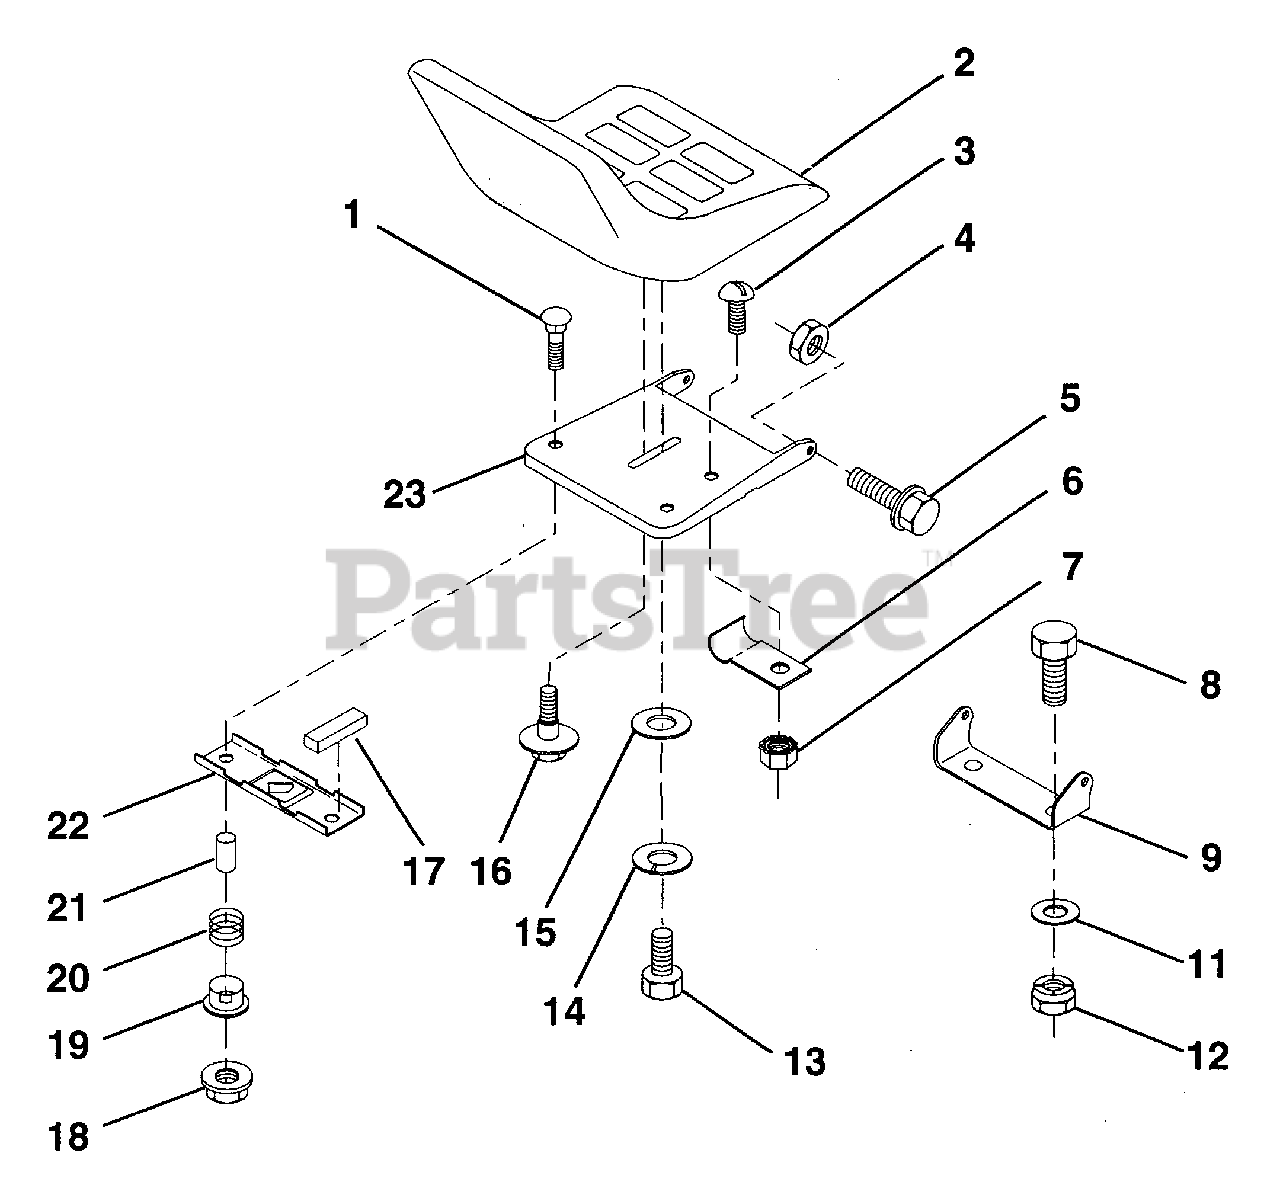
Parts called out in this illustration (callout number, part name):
1	Bolt, Carriage 1/4-20 x 1-3/8
2	Seat
3	Screw, Slotted Pan Head #10-32 x 1/2
4	Nut, Crownlock 5/16-18
5	Bolt, Shoulder 5/16-18 UNC
6	Clip, Insulated
7	Nut, Hex, Keps #10-32 UNF
8	Bolt, Hex, Fin. 3/8-16 UNC x 3/4
9	Bracket, Pivot, Seat
11	Washer 12/32 x 2 x 10 Gauge
12	Nut, Crownlock 3/8-16 UNC
13	Bolt, Hex, Fin. 1/2-13 UNC x 7/8 Grade 5
14	Washer, Lock, Heavy Helical Spring
15	Washer 17/32 x 1-3/16 x 12 Ga.
16	Bolt, Shoulder
17	Strip, Foam
18	Nut, Hex, Large, Flangelock
19	Bushing, Snap
20	Spring, Compression
21	Spacer, Split
22	Bracket, Switch Mounting
23	Pan, Seat
